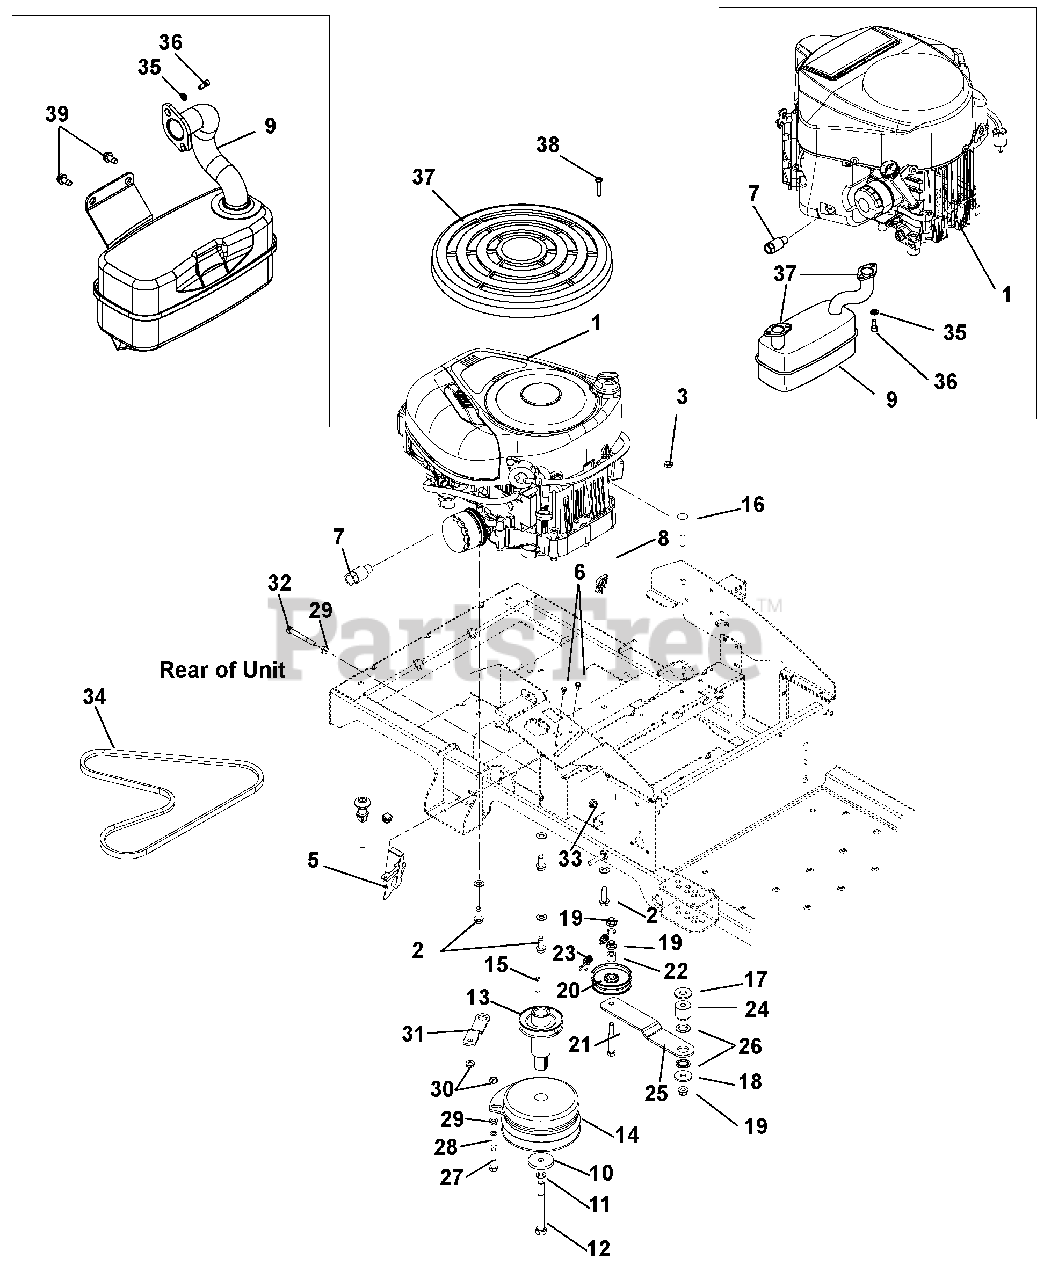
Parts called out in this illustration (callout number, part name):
1	Engine, 16.5 HP Briggs and Stratton Intek without Muffler (915146, 168)
2	Screw, Tapping .38-16 x 1.25 Hex Washer Head(915146, 168)
3	Bolt, Hex .38-16 x 1.25 (915148, 150, 170)
4	Nut, Locking Jam .375-16 (915146, 168)
5	Throttle/Choke Cable (915168)
6	Screw, Tapping 10-24 x .50 Hex Washer Head
7	Oil Drain
8	Wire Clip (for .25" hole) (148, 150, 170)
9	Muffler, Twin (915148, 150, 170)
10	Washer, Flat Steel .469 x 2.00 x .25
11	Washer, Locking .44 x .109 Regular
12	Bolt, Hex .44-20 x 4.50 Grade 8
13	Weldment, Crankshaft Extension
14	Clutch, 105 FT*LB MONO Pole
15	Key, Square .25 x 1.25 x .25 SAE 8630 or SAE 1035
16	Bolt, Round Head Square Neck .38-16 x 2.75
17	Washer, Flat Steel .563 x 1.38 x .109
18	Washer, Flat Steel .406 x 1.375 x .135
19	Nut, Locking Nylon Flange .38-16
20	Pulley, Engine Clutch
21	Bolt, Hex .38-16 x 2.75
22	Bushing, Sleeve .391 x .688 x .52
23	Spring, Extension
24	Spacer, Ground Drive Idler
25	Idler Arm, Ground Drive
26	Bushing, Idler Arm
27	Screw, Cap .31-18 x 1.75
28	Spacer, Rubber 5/16 ID x 1.0
29	Nut, Spin Lock Flange .312-18
30	Nut, Locking Top Flange .31-18
31	Bracket, Clutch Stop
32	Bolt, Hex .31-18 x 2.75
33	Nut, Locking Nylon Flange .31-18
34	V-Belt, HA-RAW Edge Laminated
35	Washer, Locking .31 x .078 Regular (915148, 150, 170 )
36	Capscrew .31-18 x .75 S/HD (915148, 150, 170)
37	Guard, Briggs Engine (915146, 168)
38	Screw, 8-16 x .87 (915146, 168)
39	Screw, Tapping .25-20 x .50 Hex Washer Head (915146, 168)
